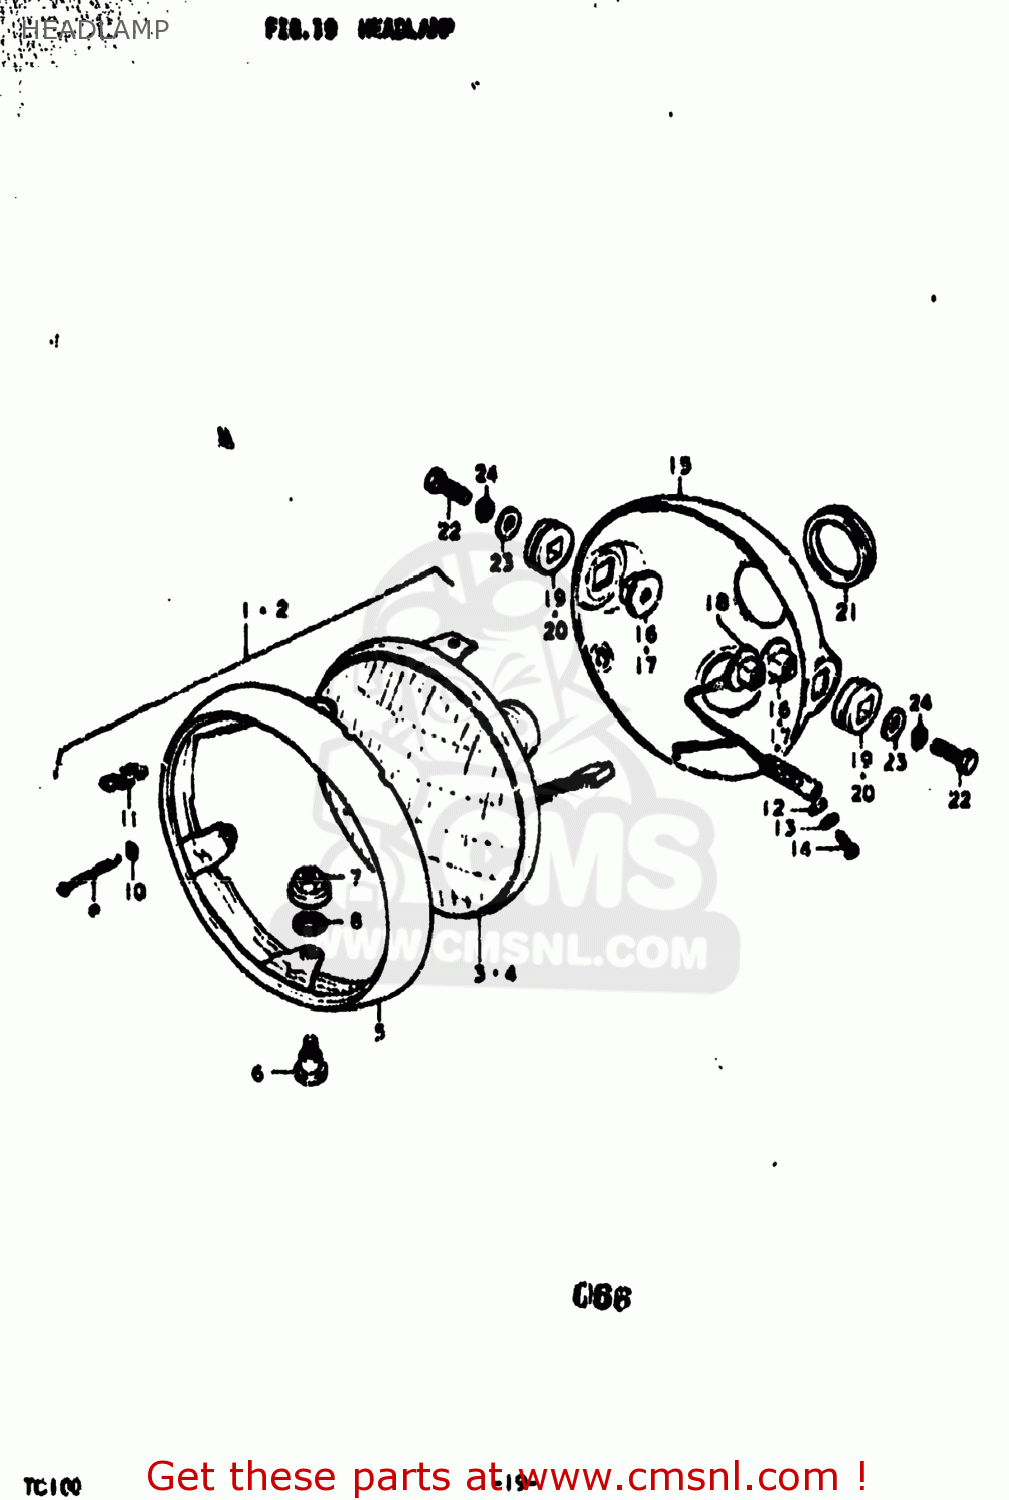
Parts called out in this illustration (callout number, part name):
1	HEADLAMP ASSEMBLY
2	LAMP ASSEMBLY,HEAD
3	LAMP UNIT
4	UNIT,HEADLAMP
5	RIM,HEADLAMP
6	SCREW
7	NUT,ADJUSTING
8	SPACER,HEADLAMP UNIT
9	SCREW,HEADLAMP ADJUST
10	NUT,HEADLAMP ADJUSTER
11	SPRING,HEADLAMP ADJUST
12	WASHER
13	LOCK WASHER
14	SCREW
15	HOUSING COMP,HEADLAMP
16	SPACER, HOUSING RH
17	SPACER,HEADLAMP HOUSING
18	SPACER,HEADLAMP HOUSING
19	CUSHION,HEADLAMP HOUSING
20	CUSHION,HEADLAMP HOUSING
21	GROMMET,HEADLAMP HOUSING
22	BOLT
23	WASHER
24	LOCK WASHER
